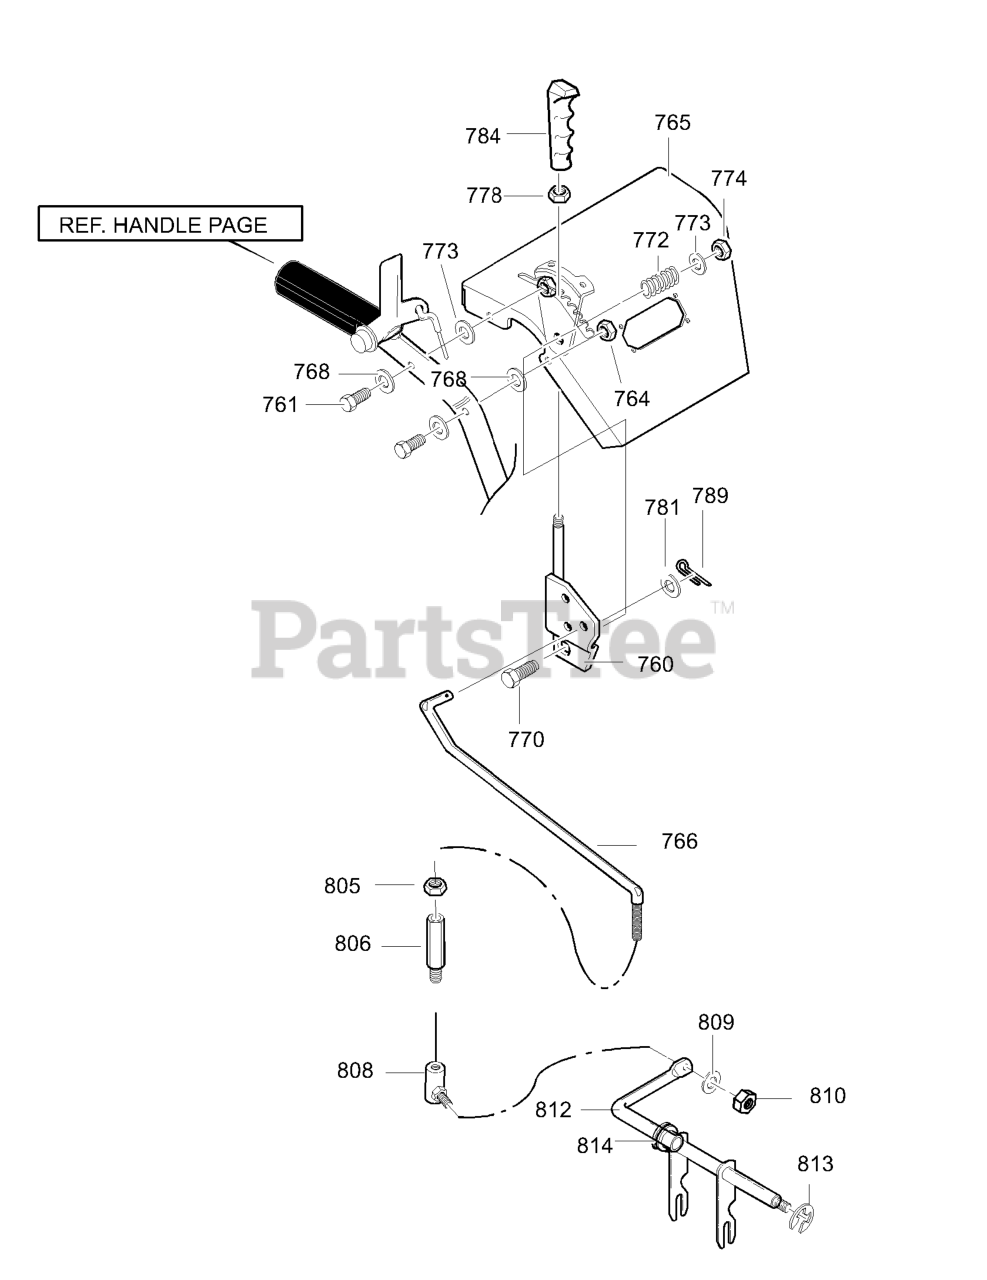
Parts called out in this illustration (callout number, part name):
760	HANDLE ASSY SPD CTRL
761	SCREW, 5/16-18 x 1.75
764	NUT, 5/16-18
765	ASSY. BAY PANEL - LT
766	ROD, SPEED CONTROL
768	WASHER
770	SCREW 3/8-16X2.00
773	FLATWASHER
774	NUT, 3/8-16
778	NUT, 3/8-16
781	FLATWASHER
784	GRIP, LEVER
789	PIN, COTTER
805	NUT, 5/16-18
806	ADAPTER, SPEED ROD -YZ
808	BALLJOINT, STEEL -YZ
809	WASHER
810	NUT, 5/16-18
812	ROD, ASSY YOKE
813	RING, RETAINER
814	BEARING, FLANGE
